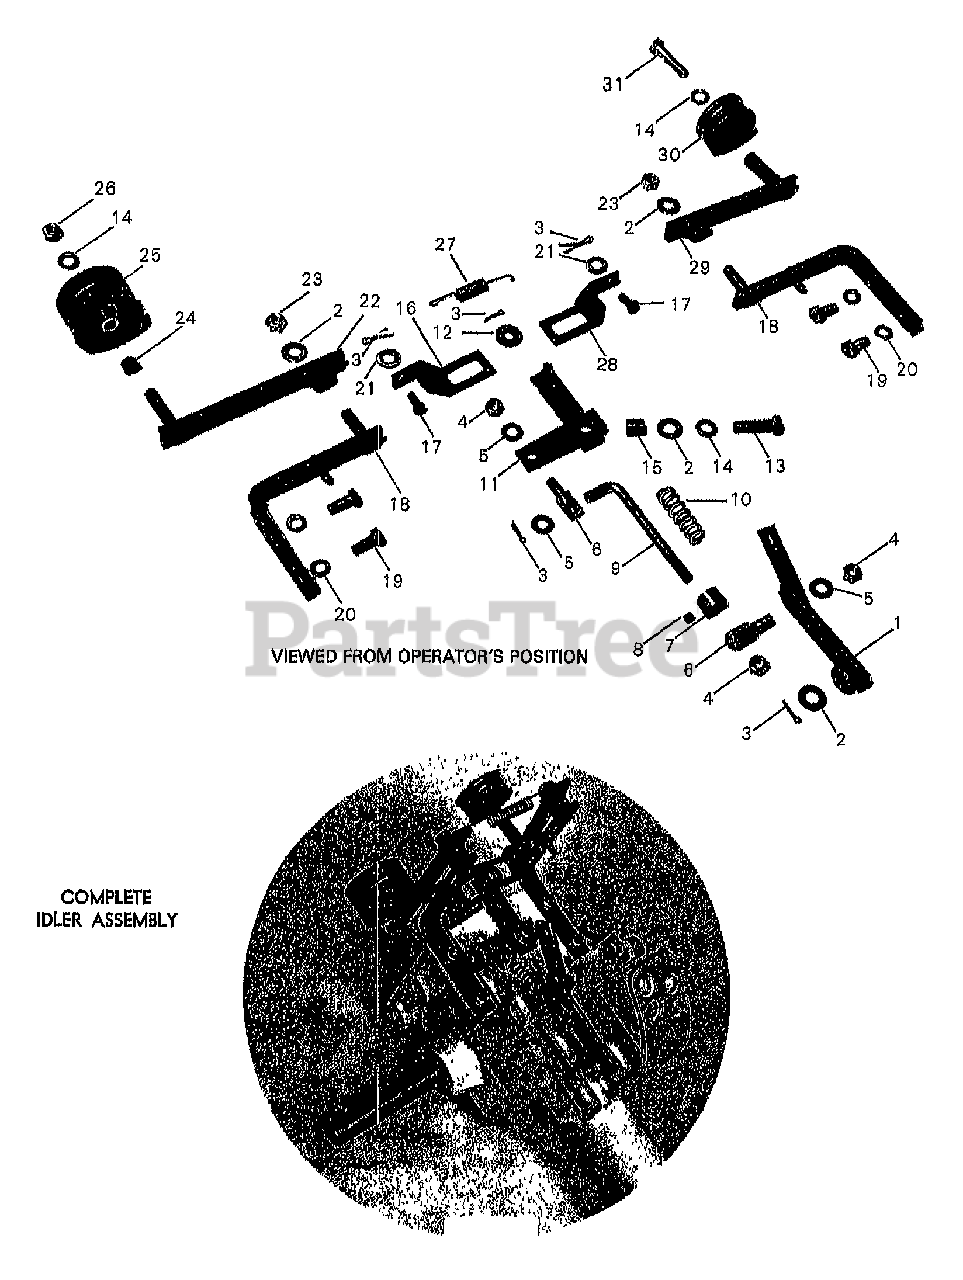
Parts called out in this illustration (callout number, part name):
1	LEVER-WELD REAM (FORWARD/REVERSE)
2	WASHER-FLAT 3/8 SAE
3	PIN-COTTER .09X.625
4	NUT-H/LK 5/16-18
5	WASHER-FLAT 5/16 SAE
7	COLLAR-ADJUST
8	SCR-SS 1/4-20 X .25 (WITH BRASS TIP)
9	ROD-CONNECTING
10	SPRING-.48 X 3
11	BELLCRANK-WELD ZP
12	WASHER-#1X .316 X.062 ZP
13	SCR-HH 3/8-16X1.25
14	WASHER-LK .375 @ DEPL
15	BUSHING-.5X.375X.53 (FITS IN #20345 BELLCRANK)
16	LINK-IDLER ARM LT
17	PIN-CLEVIS .375X.719 (TAKES COTTER PIN)
18	BRKT-IDLER SUPPORT
19	SCR-HH 5/16-18X1.0 G5 ZP
20	WASHER-LK .312 ZP
21	WASHER-FLAT 1/4 SAE
22	ARM-IDLER FWD WELD
23	NUT-H/LK 3/8-16
24	BUSHING-.5X.375X.3
25	PULLEY-FWD IDLER
26	NUT-HEX 3/8-16 ZP
27	SPRING-.406 X 3.125
28	LINK-IDLER ARM RT
29	ARM-IDLER REV WELD
30	PULLEY-REV IDLER
31	BOLT-HH 3/8-16X1.5 FTH ZP
